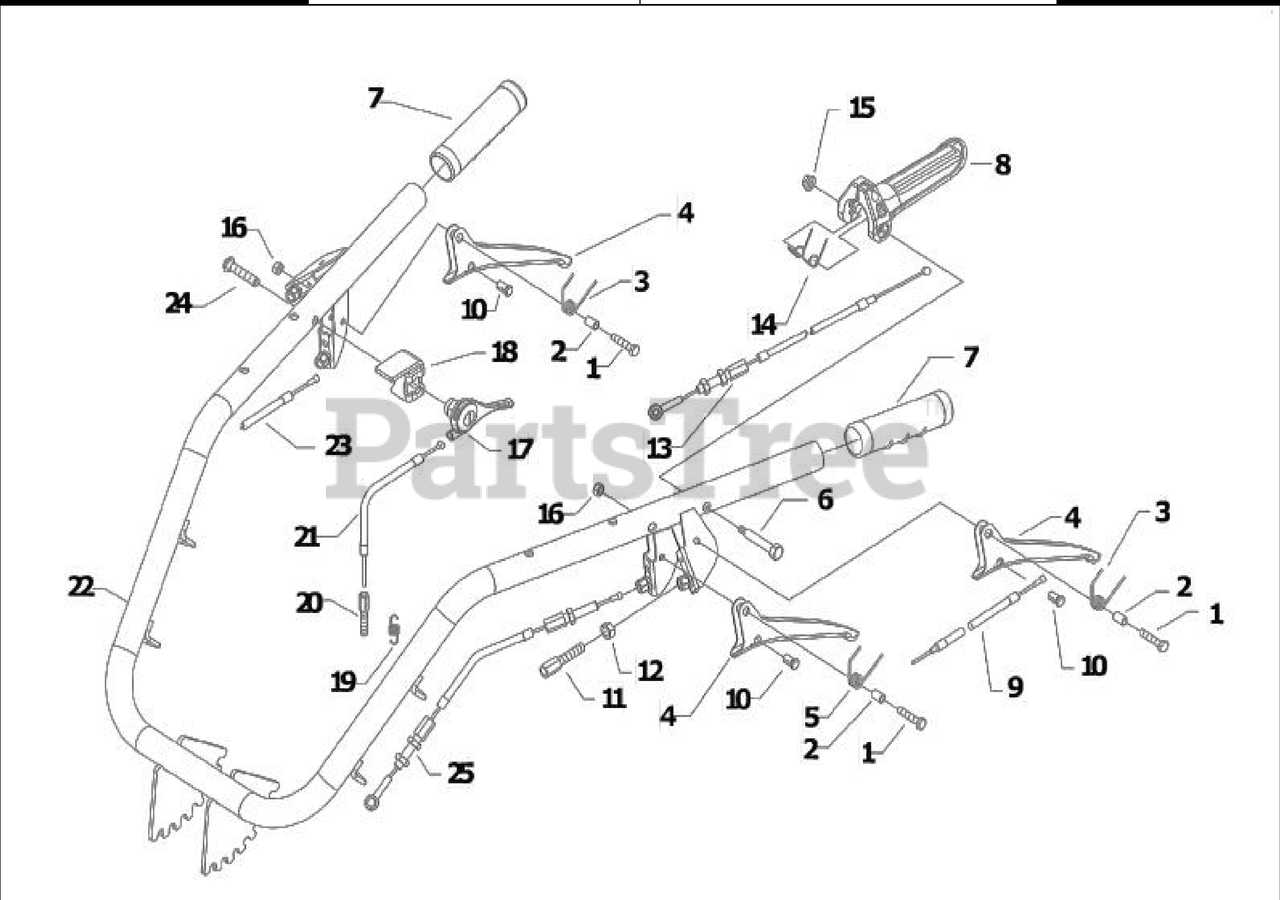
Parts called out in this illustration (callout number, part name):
1	SCREW TE M6X25 UNI 5739 8G
2	SPACER
6	LEVER PIN
8	LEVER OPC (Operators Presence Control)
9	BRAKE CABLE
10	CABLE CLAMP
11	ADJUSTING SCREW M8
13	OPC CABLE
14	SPRING
15	SELFLOCK NUT M6
16	HEXAGON SELFLOCK NUT M6
17	THROTTLE CONTROL LEVER
18	PANEL
19	RESTORING SPRING
20	ADJUSTING SCREW
21	THROTTLE CABLE
22	HANDLEBAR
23	STEERING RELEASE CABLE
24	SCREW TBCEI M8X40 ISO7380 10K Z
25	CLUTCH CABLE
